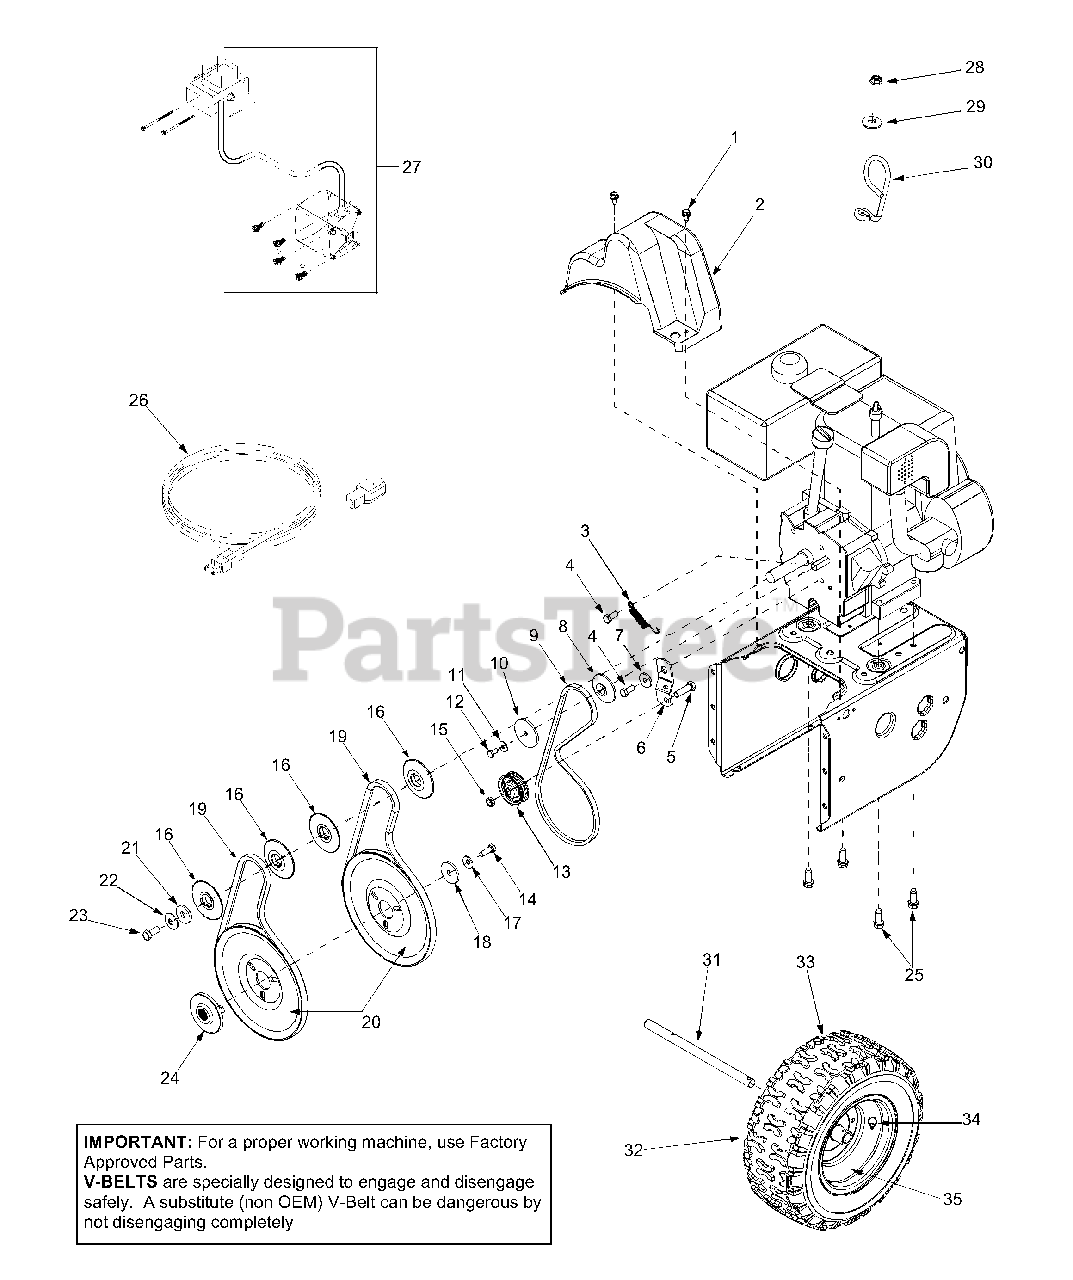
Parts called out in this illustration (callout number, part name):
1	Hex Washer Screw 1/4-20 x .625
2	Belt Cover
3	Extension Spring
4	Hex Screw 5/16-24 x .75
5	Hex Cap Screw 3/8-16 x 1.25
8	Pulley Half
9	V-Belt
10	Pulley Half
11	Bell Washer
12	Hex Cap Screw 1/4-28 x .50
13	Flat Idler
14	Lock Hex Cap Screw 5/16-24
15	Lock Jam Nut 3/8-16
16	Pulley Half
17	Bell Washer
18	Flat Washer
19	Belt
20	Auger Pulley
21	Flat Washer 3/8 x 1.25 OD
22	Bell Washer
23	Hex Cap Screw 3/8-24
24	Adapter Pulley
25	Hex Screw 3/8-16 x 1.0
26	Extension Cord
27	Electric Start Kit
28	Lock Nut, 1/4-20
29	Flat Washer, .28 x .74 x .063
30	Cable Guide
31	Axle: .75 dia. x 12.2" Lg.
33	Tire 16.0" x 6.5" x 8" (1150W)
34	Tubeless Air Valve
